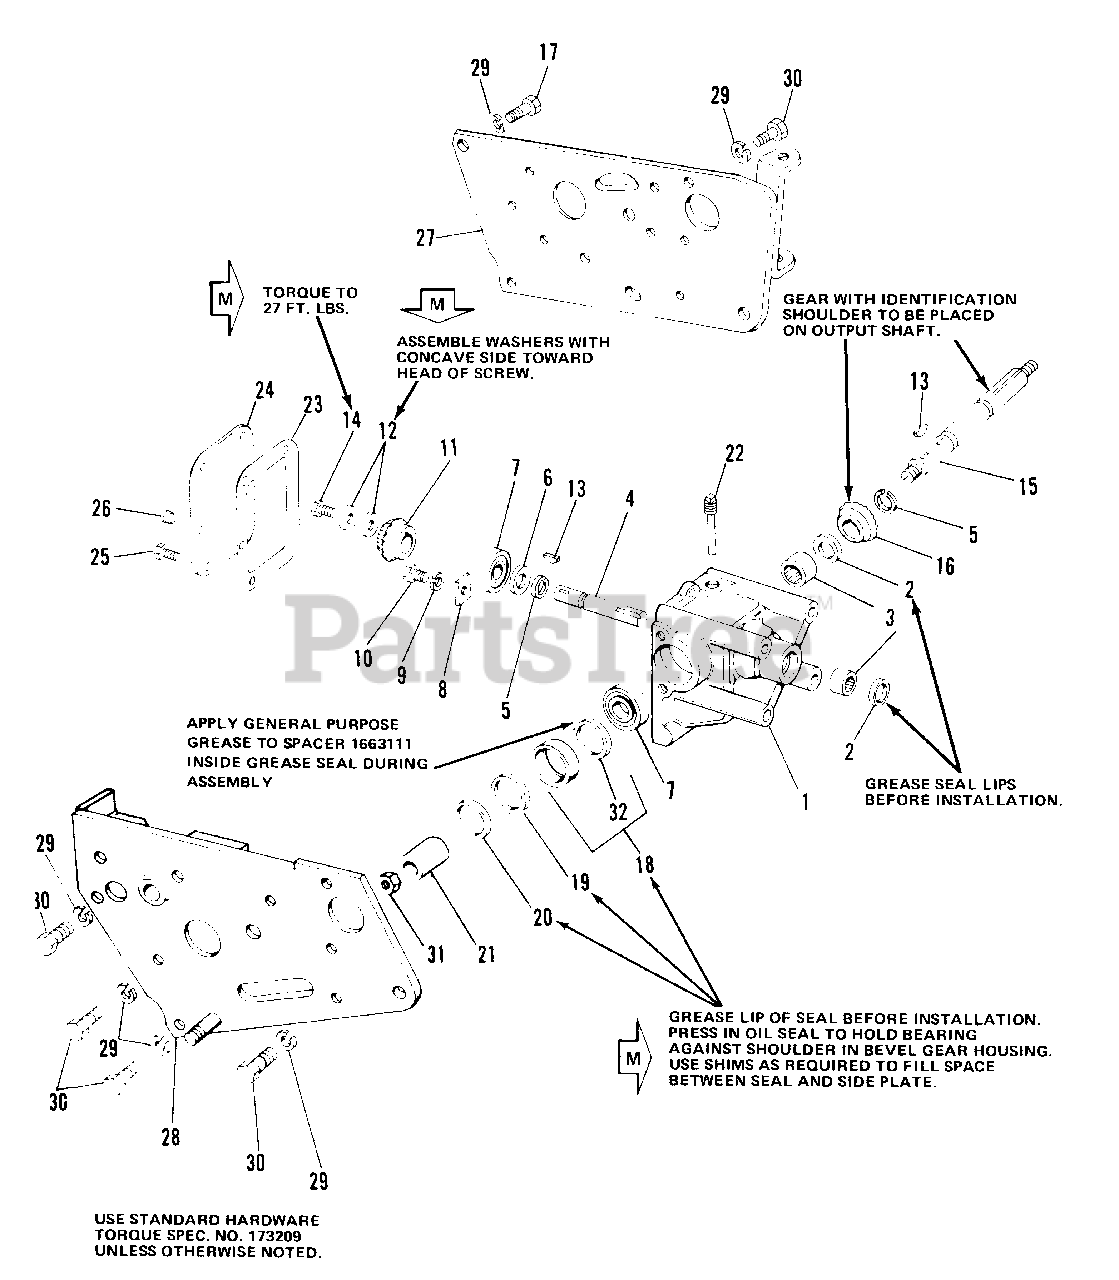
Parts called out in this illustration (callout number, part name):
1	HOUSING, Bevel Gear
3	BEARING, Needle
4	SHAFT, Driver
5	RING, Retaining
7	BEARING, Ball
8	PLATE, Bearing Clamp
9	LOCKWASHER, 5/16
10	CAPSCREW, Hex Hd., 5/16-18 x 5/8
11	GEAR, Bevel Driver
13	KEY, Woodruff, No. 9
14	CAPSCREW, Hex Hd., 5/16-18 x 3/4
15	SHAFT, Driven
16	GEAR, Bevel Driven
17	CAPSCREW, Hex Hd., 7/16-14 x 1-1/4
25	CAPSCREW, Hex, 1/4-20 x 5/8
27	PLATE ASSY, Side, L.H.
28	PLATE ASSY, Side, R.H.
29	LOCKWASHER, 7/16
30	CAPSCREW, Hex Hd., 7/16-14 x 1
31	LOCKNUT, Hex, Jam, 3/4-16
32	SPACER, Oil Seal
